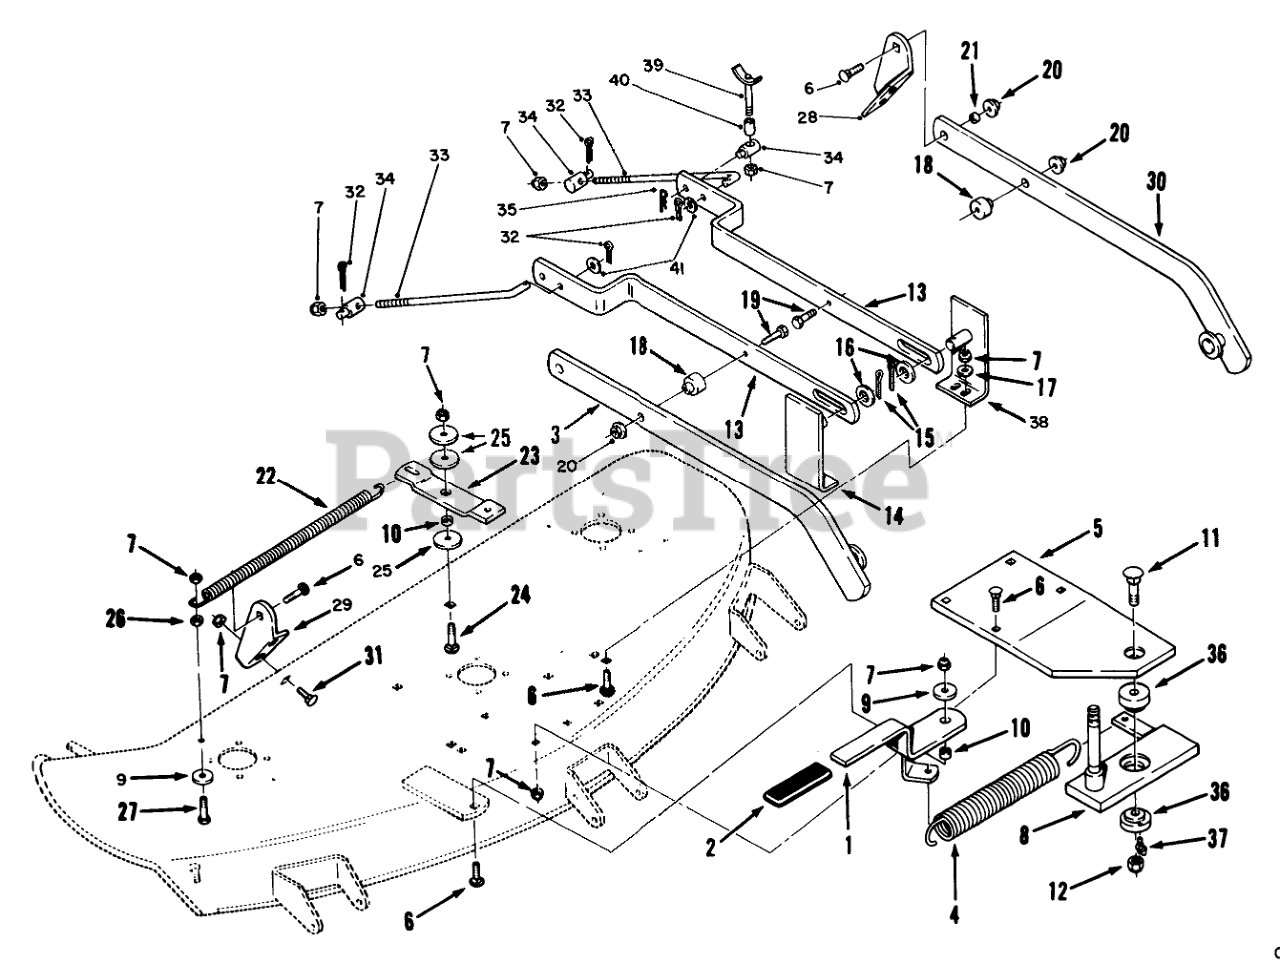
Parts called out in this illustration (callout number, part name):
1	Lever
3	Draft Bar RH
4	Spring
5	Plate
6	BOLT-CARR
7	NUT-LOCK, NI
8	Countershaft
9	WASHER
10	SPACER
11	Bolt
12	NUT-LOCK, NI
13	Bar-Leveler
14	Bracket L.H.
15	PIN-COTTER
16	WASHER-FLAT
17	WASHER-FLAT
18	SPACER
19	SCREW-HH
20	LOCKNUT-FLANGE
21	SPACER
22	SPRING - EXTENSION
23	Arm-Idler
24	SCREW-CARR
25	Washer
26	NUT-HEX
27	SCREW-HH
28	Bracket LH
29	Bracket RH
30	Draft Bar LH
31	BOLT-CARR
32	PIN-COTTER
34	TRUNNION
35	Hairpin Cotter
36	BUSHING
37	Fitting-Grease
38	Bracket R.H.
39	WLDMT-HANGER ROD
40	SPACER .375 ID X 1.6
41	WASHER-PLAIN
